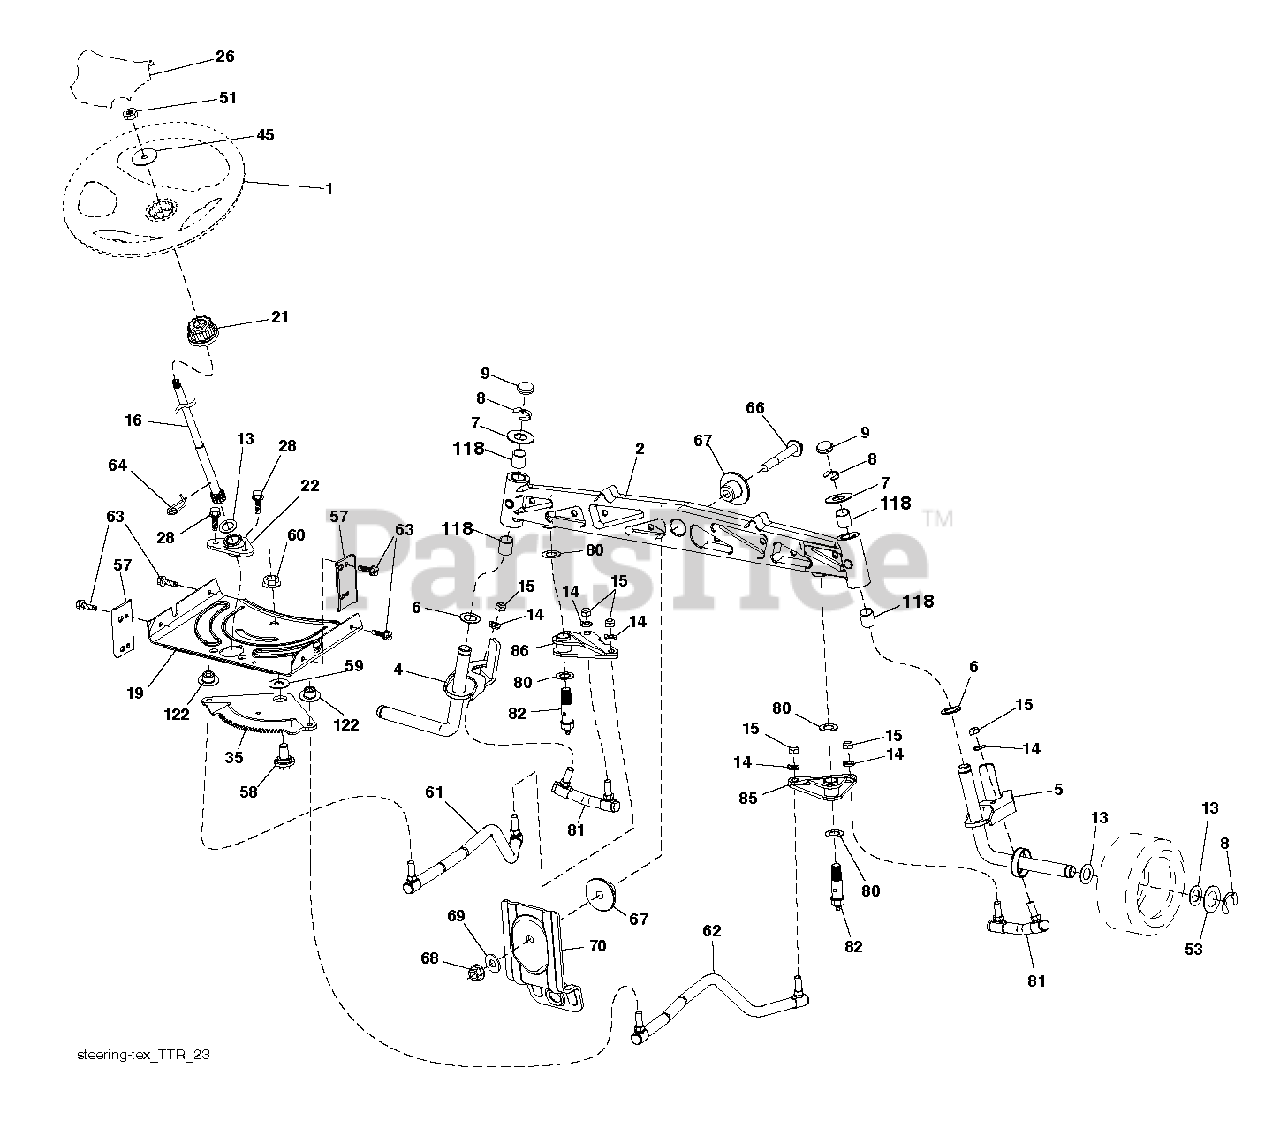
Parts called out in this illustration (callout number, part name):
1	WHEEL.STEER.HUSQ.SR.498.OVMLD
2	RP SUBASM.AXLE.CAST.NZTR.
4	SPINDLE WELDMENT.SPINDLE.LH.15
5	SPINDLE WELDMENT.SPINDLE.RH.15
6	THRUST WASHER
9	CAP.SPINDLE.BLACK
14	WASHER, LOCK 3/8
15	NUT CROWNLOCK 3/8-24
16	SHAFT SHAFT.STEERING.2HIGH.PLA
19	PLATE.STEER.DDL.NLT/NG
21	RP STEERING.WHEEL.ADAPTER
22	BUSHING.ASM.STEERING.A
26	INSERT.CAP.WHL.STRG.HUSQ.PREM
28	SCREW, 3/8-16X3/4
35	GEAR GEAR.SECTOR.TEX.NZTR
45	WASHER 9/16"ID, 2 3/8"OD
51	NUT.HEX.1/2-20
53	WASHER.HARDENED
57	BRACKET.UPSTOP.TEX
58	BOLT.SHOULDER.SECTOR.P
59	WASHER.THURST.SECTOR.S
60	NUT FLANGE LOCK 5/8-11
61	LINK ASSY DRAGLOINK, ADJUSTABL
62	DRAGLINK,ADJUSTABLE,RH
63	SCREW
64	RETAINER.CLIP.SPRING.S
66	BOLT HEX FGHD 7/16-14 X 3 SERR
67	BUSHING.PM.FRONT AXLE
68	NUT.LOCK.FLANGE.7/16
69	WASHER.1.5X.505X.118
70	BRACKET.FRT.DECK.SUSP.RR.MT431
80	THRUST WASHER
81	LINK SUBASM.LINK.CROSS.NZTR
82	SUBASM;PIVOT;BOLT;NZTR
85	PIVOT SUBASM.PIVOT.RH.NZTR
86	PIVOT SUBASM.PIVOT.LH.NZTR
118	BUSHING, AXLE CAST
122	CAP.GEAR.SECTOR.TEX
